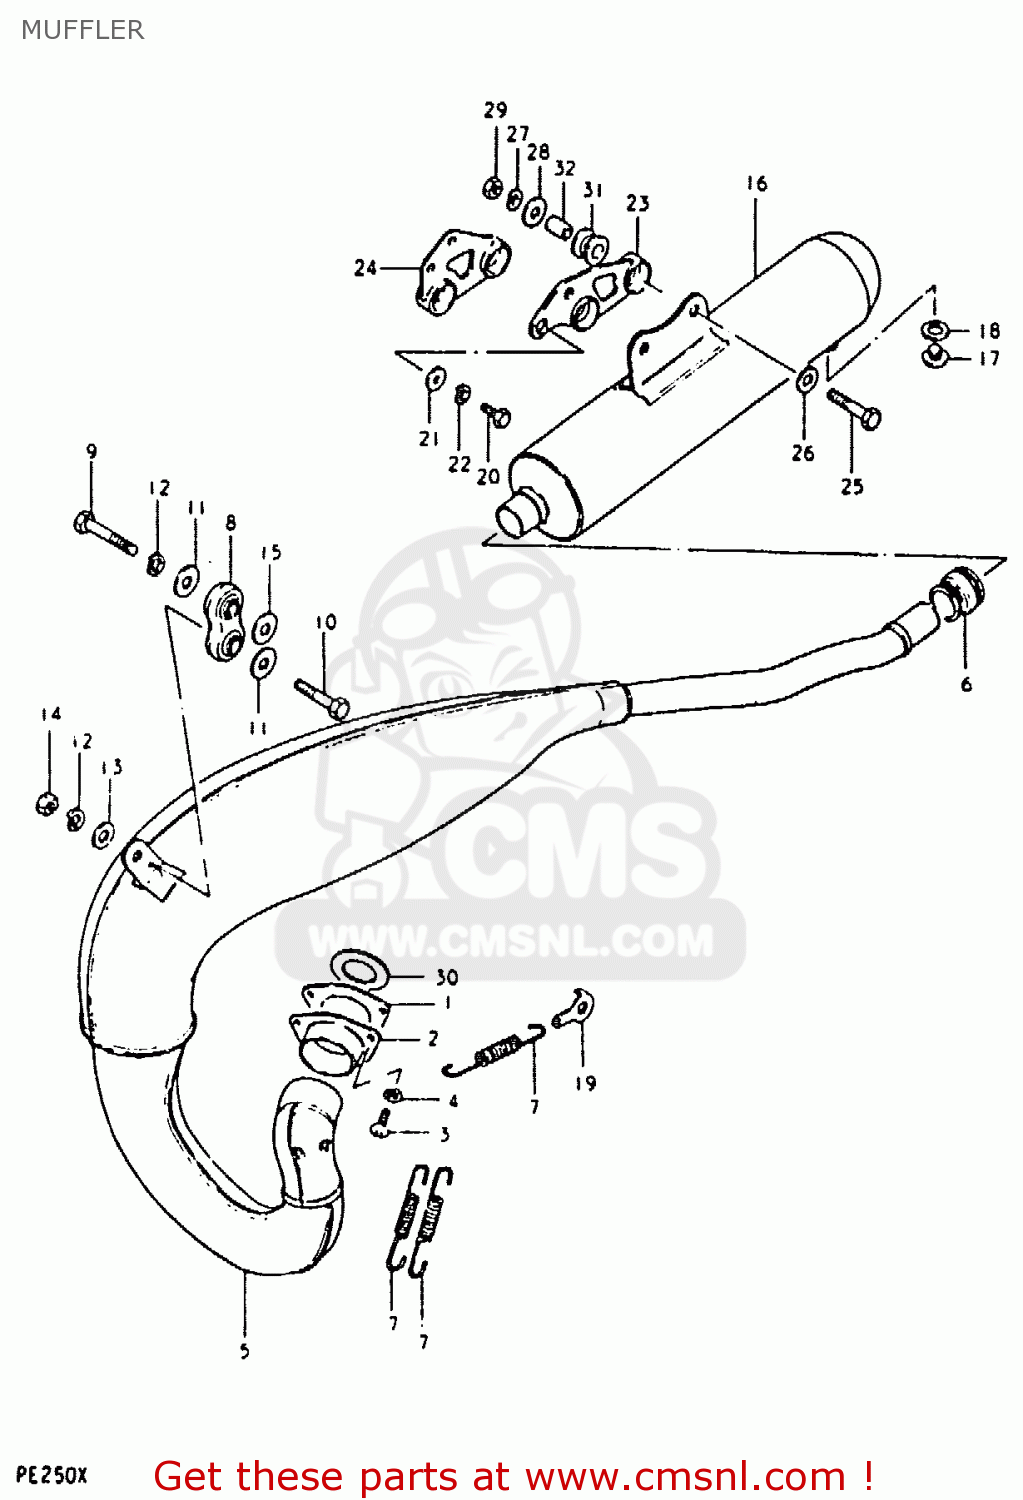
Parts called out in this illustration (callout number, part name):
1	GASKET,EXHAUST PIPE (MCA)
2	FLANGE,EXHAUST PIPE
3	SCREW
4	LOCK WASHER
5	BODY,MUFFLER
6	CONNECTOR,MUFFLER
7	SPRING
8	DAMPER,MUFFLER
9	BOLT 8X45
10	BOLT
11	WASHER
12	LOCK WASHER
13	WASHER
14	NUT
15	SPACER(8.4X12X12)
16	MUFFLER ASSY, 2ND
17	PLUG, DRAIN
18	GASKET(12X16X2) (NAS)
19	HOOK,MUFFLER FIT SPRING
20	BOLT
21	WASHER
22	LOCK WASHER
23	DAMPER,MUFFLER SUPPORT
24	DAMPER,MUFFLER SUPPORT
25	BOLT
26	WASHER
27	LOCK WASHER
28	WASHER (8.5X29X1.6)
29	NUT
30	PLATE, EXHAUST PIPE
31	CUSHION
32	SPACER (8.2X12X17)
